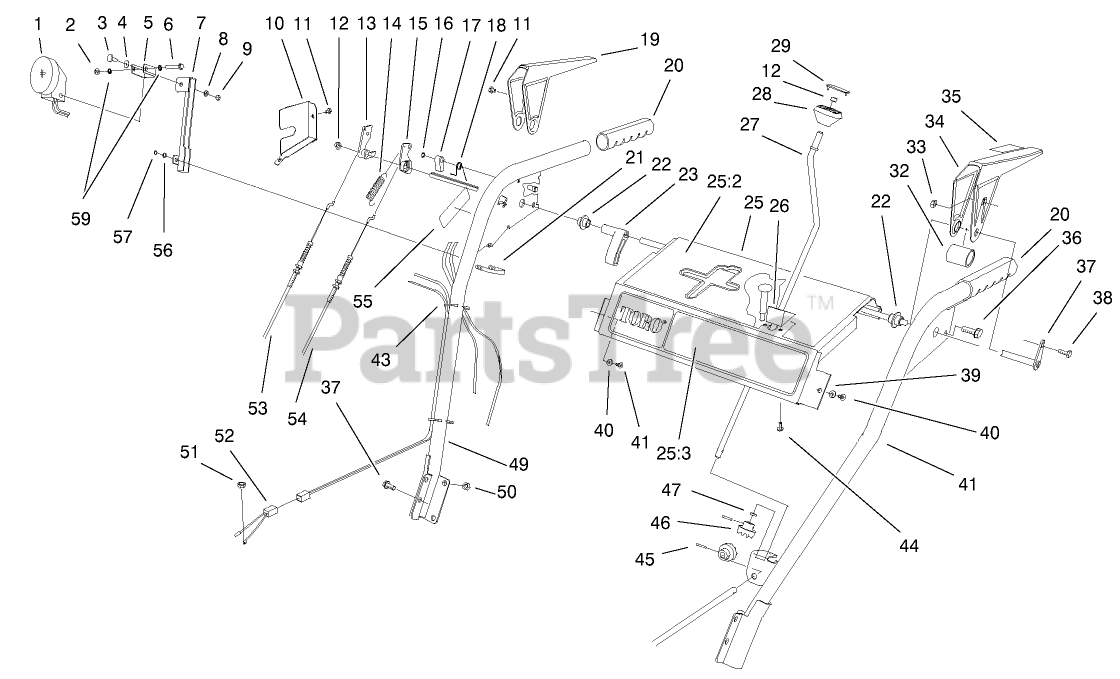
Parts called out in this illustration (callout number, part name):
1	HEADLAMP ASM
2	NUT-HF
3	BOLT-CARR
4	WASHER-FLAT
6	SCREW-HH
7	MOUNT ASM-LIGHT
8	WASHER-LOCK
9	NUT-HEX
10	COVER-LOCK, LEVER
12	NUT-PUSH
14	SPRING-EXTENSION
15	CAM-RELEASE
16	RING-RETAINING
17	LATCH-LOCKING
18	SPRING-TORSION
19	LEVER-TRACTION, RH
20	GRIP-HANDLE
21	U-BOLT
22	BUSHING-LEVER
23	LEVER-TRIP
25	CONTROL PANEL ASM
25:2	DECAL-CONTROL
25:2	DECAL-PANEL, TOP
25:3	DECAL - FRONT PANEL
25:3	DECAL - PANEL FRONT
26	PLATE-GUIDE
27	CRANK-ROD, CHUTE
28	KNOB-CONTROL, CHUTE
29	COVER-KNOB
32	SPACER-LEVER, TRACTION
33	NUT-LOCK, NI
34	LEVER-TRACTION, LH
35	DECAL-LEVER
36	SCREW-HWHTF
37	CROSS ROD ASM
38	SCREW-HWH
39	WASHER-FLAT
40	SCREW-HWHTF
41	LH HANDLE ASM, 24"-32"
43	TIE-CABLE
44	SCREW
45	PIN-SPRING
46	GEAR-UNIVERSAL
47	WASHER-RUBBER
49:2	DECAL-WARNING
49:2	DECAL-ADJUSTMENT
50	NUT-LOCK, NI
51	NUT-HEX
52	WIRE ASM
53	CABLE-IMPELLER
54	CABLE-TRACTION
56	WASHER-PLAIN
57	NUT-LOCK, NI
59	WASHER-LOCK
